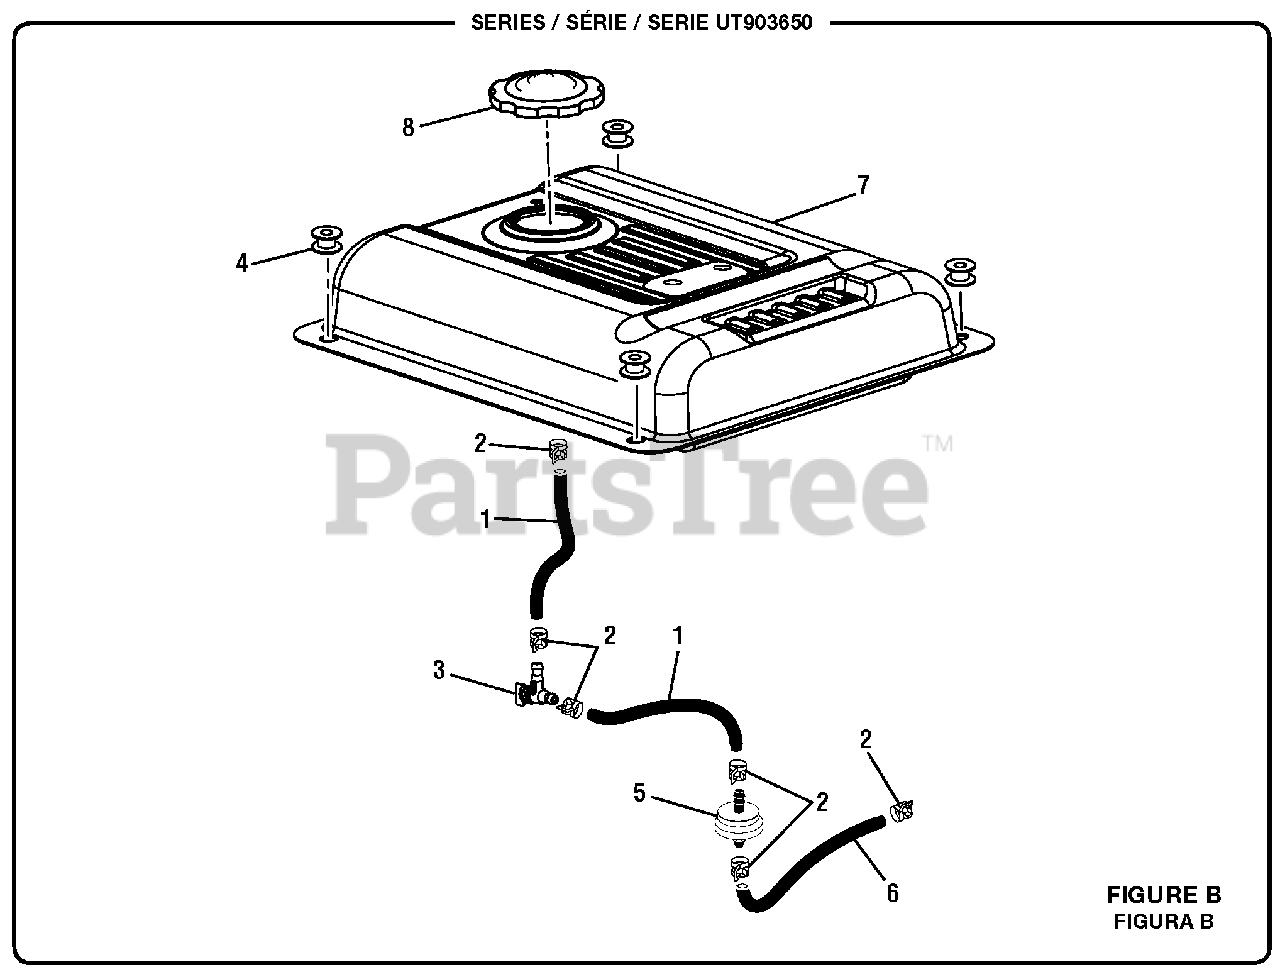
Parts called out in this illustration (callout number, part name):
1	Fuel Line (On Filter)
2	Fuel Line Clamp
3	Fuel Shut Off Valve
4	Bushing w/Insert
5	Fuel Filter
6	Fuel Line
7	Fuel Tank
